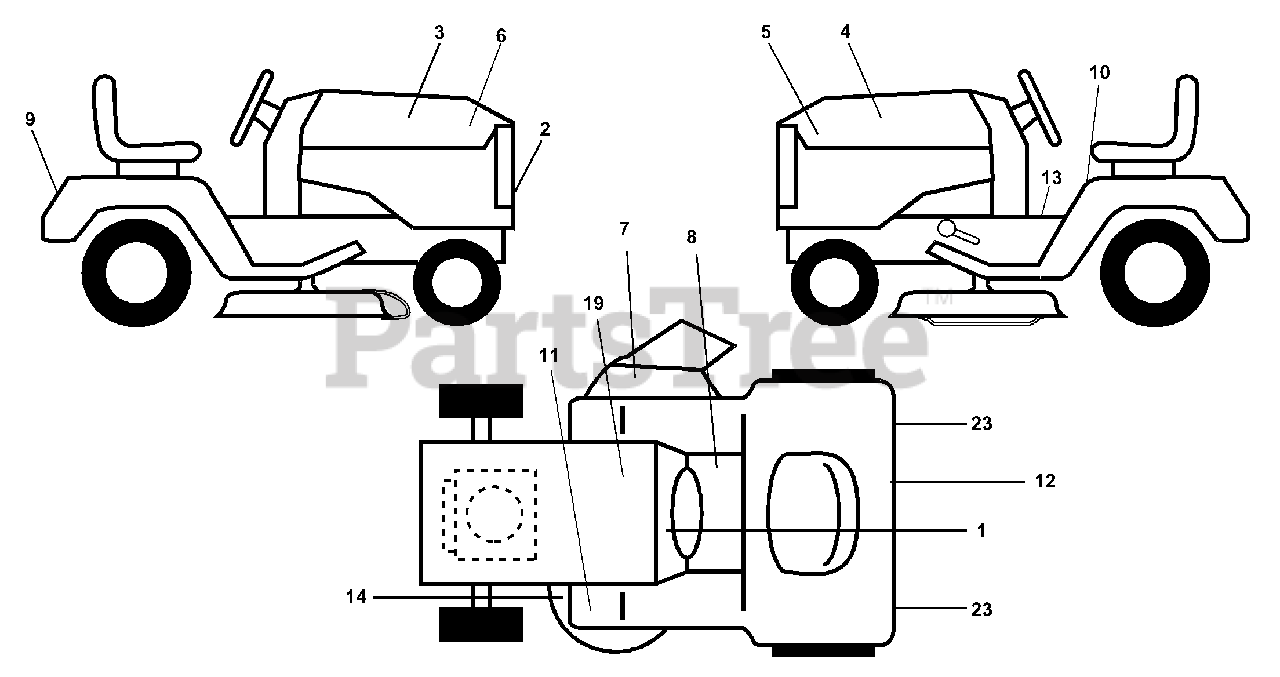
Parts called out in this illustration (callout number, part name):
1	Decal, Operating Instruction
2	Decal, Grille Husqvarna "H" Logo
3	Decal, Hood, RH
4	Decal, Hood, LH
5	Decal, Inst Hood LH GTH200 Hydro
6	Decal, Insrt Hood RH GTH200 Hydro
7	Decal, Warning Multi-Language
8	Decal, Brake Parking Saddle
9	Decal, Fender
10	Decal, Caution
11	Decal, Clutch/Brake
12	Decal, D-Bar Ctrl. Mvt Hyd YT/GT
13	Decal, Sdl Cold Start Hyd E/F
14	Decal, V-Belt Schematic
19	Decal, Battery
23	Reflector, Taillight
